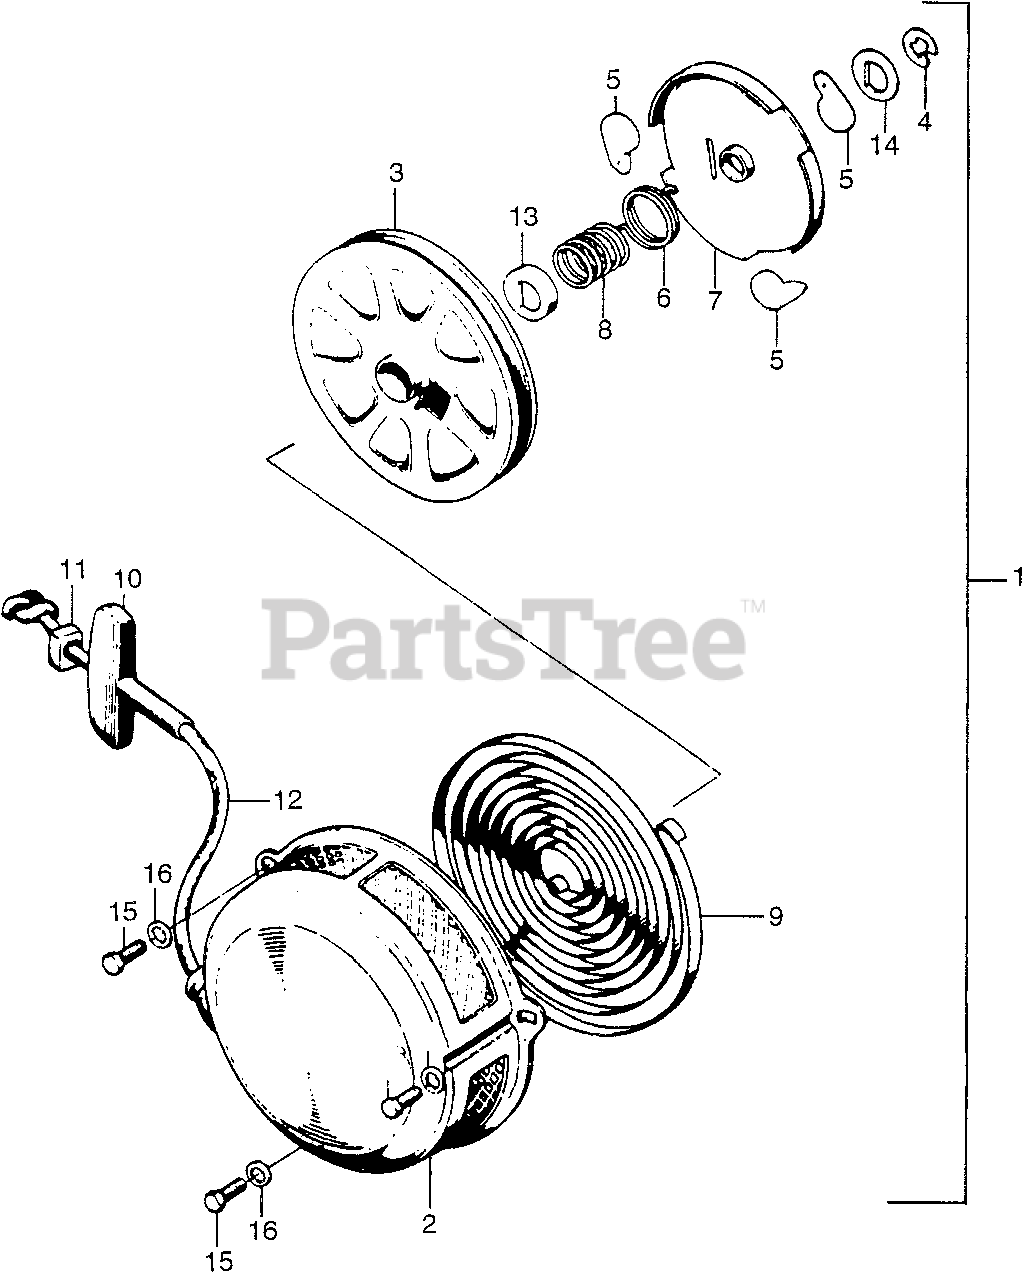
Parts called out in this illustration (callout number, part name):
1	STARTER ASSY., RECOIL *R8* (BRIGHT RED)
2	CASE, RECOIL STARTER *R8* (BRIGHT RED) (NOT AVAILABLE)
2	CASE, RECOIL STARTER *R8* (BRIGHT RED)
3	PULLEY, RECOIL STARTER
5	RATCHET, STARTER
6	SPRING SET
7	PLATE, FRICTION
8	SPRING, FRICTION
9	SPRING, STARTER RETURN
10	KNOB SET, STARTER
12	ROPE, RECOIL STARTER (#6X54")
13	WASHER A (NOT AVAILABLE)
15	BOLT, HEX. (6X12)
16	WASHER, PLAIN (6MM)
